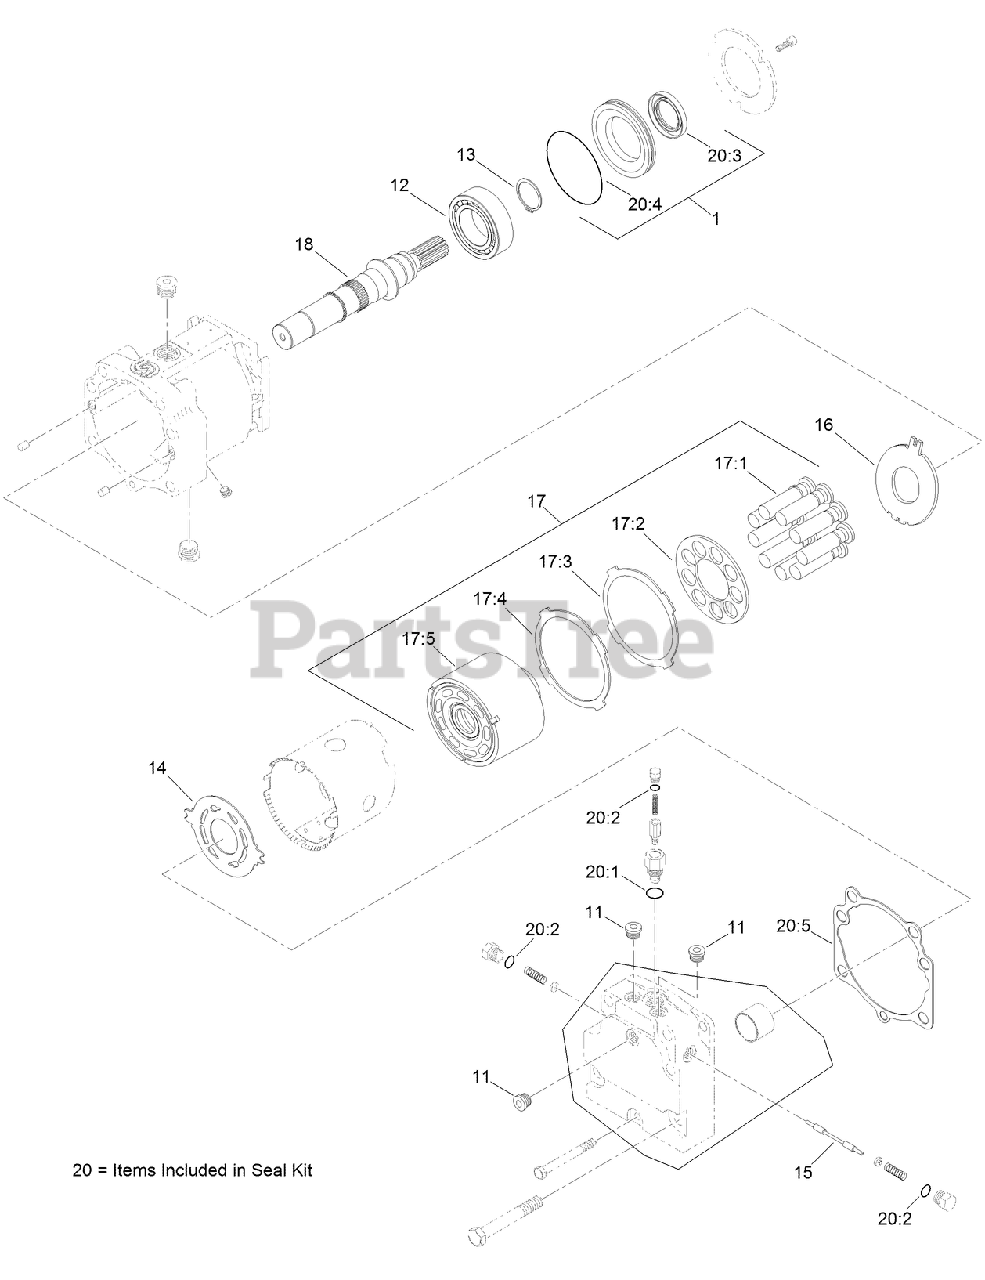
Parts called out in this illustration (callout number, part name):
1	SHAFT SEAL KIT
11	PLUG ASM
12	BEARING-ROLLER
13	RING-RETAINING
14	PLATE-VALVE
15	SPOOL-SHUTTLE
16	PLATE-THRUST
17	CYLINDER BLOCK KIT W/ SPEED RING
17:1	PISTON-WELDED
17:2	GUIDE-SLIPPER
17:3	RETAINER-GUIDE, SLIPPER
17:4	SHIM-RETAINER, SLIPPER GUIDE
17:5	CYLINDER BLOCK ASM
20	OVERHAUL SEAL KIT
20:1	O-RING
20:2	O-RING
20:3	LIP SEAL
20:4	O-RING
20:5	GASKET-CAP, END
